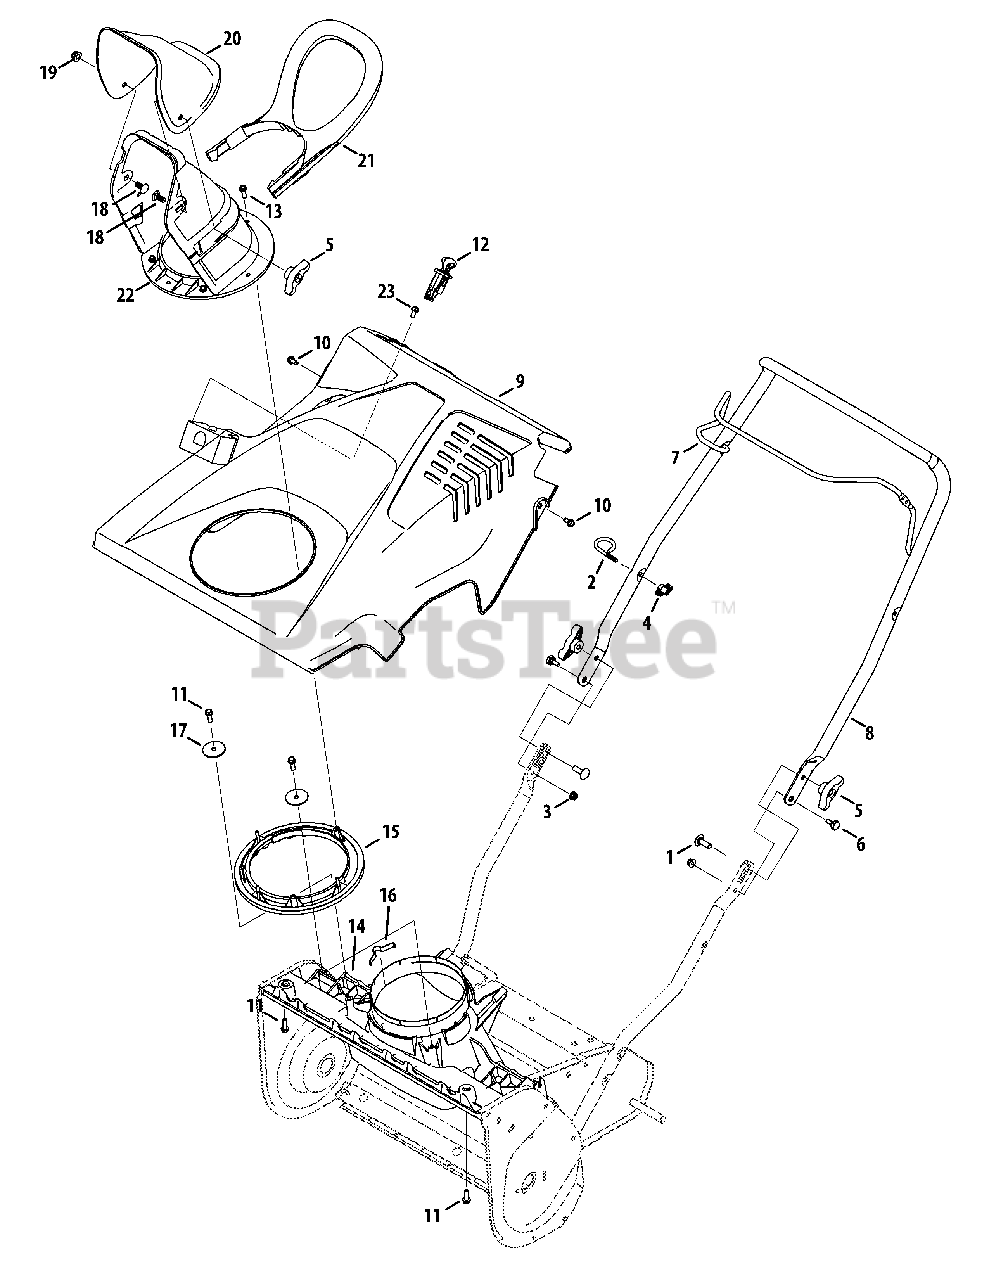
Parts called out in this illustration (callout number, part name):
1	Carriage Bolt, 5/16-18 x 1.00
2	Eye Bolt, 1/4-20
3	Flange Lock Nut, 1/4-20
4	Knob Handle
5	Wing Knob
6	Shoulder Screw, .375 x .148 x 1/4-20
7	Auger Bail
8	Upper Handle
9	Top Cover (Black w/o electric start)
9	Top Cover (Gray)
9	Top Cover (Black)
10	Hex Screw, 1/4-14 x .500
11	Screw, Hi-Lo:1/4-15, 0.75
12	Ignition Switch Assembly
13	Hex Washer Screw, 1/4 x .750
14	Chute Adapter
15	Chute Ring
16	Chute Adjustment Spring
17	Flat Washer, .28 x 1.5 x .066
18	Carriage Bolt, 5/16-18 x .750
19	Flange Lock Nut, 5/16-18
20	Upper Chute
21	Chute Handle
22	Lower Chute
23	Hex Washer Screw, 1/4-15 x .50
